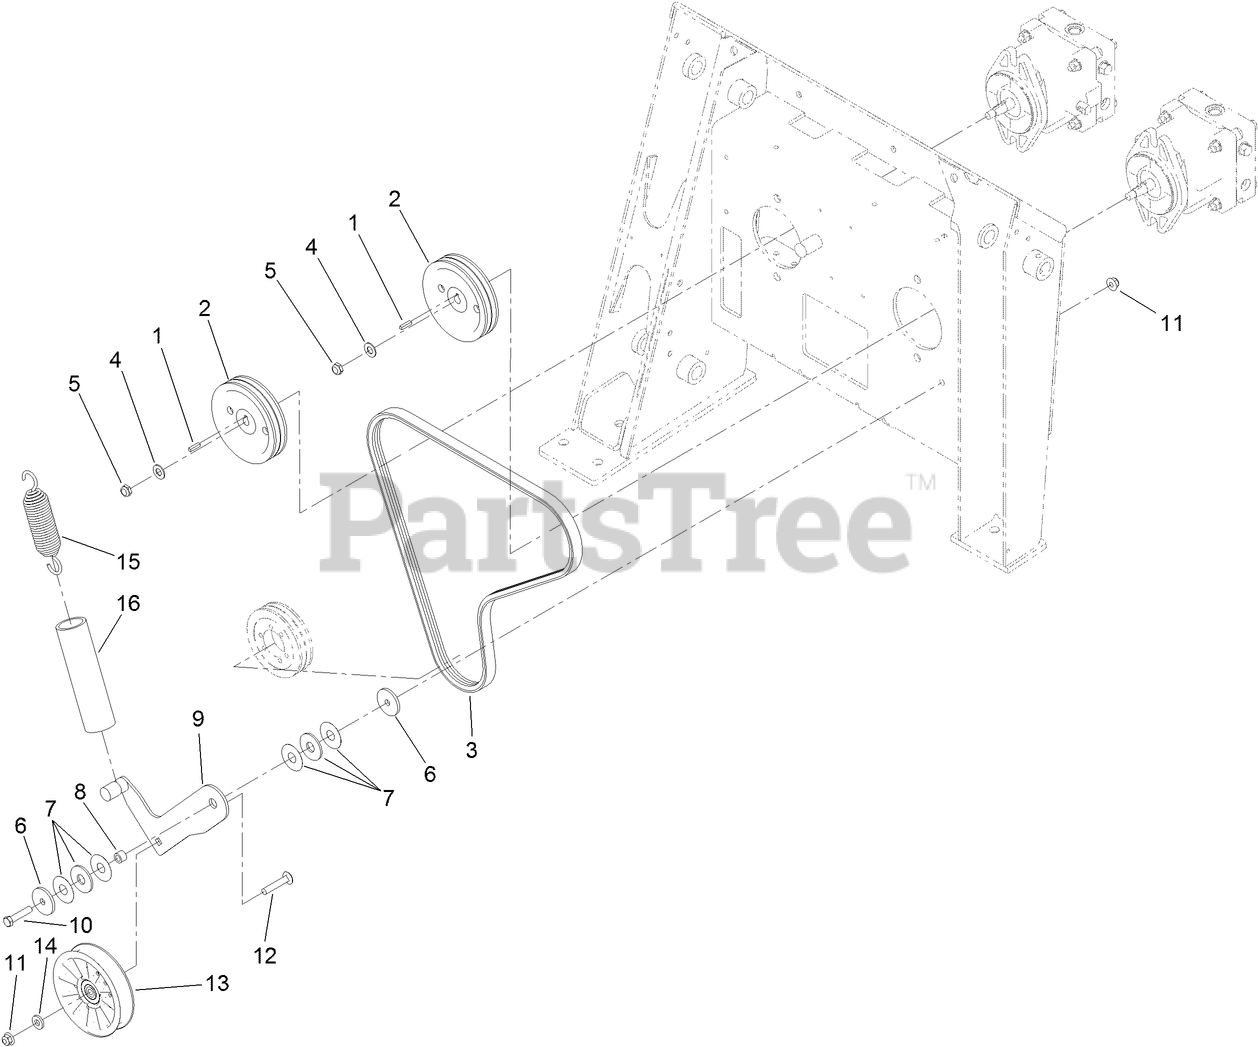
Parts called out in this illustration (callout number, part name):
2	PULLEY-3V
3	V-BELT
4	WASHER-FLAT
5	NUT-LOCK, NI
6	WASHER-PLAIN
7	WASHER-FRICTION, COMPOSITE
8	SPACER
9	ARM-IDLER
10	SCREW-HH
11	NUT-HF, NI
12	BOLT-CARRIAGE
13	PULLEY-IDLER
14	SPACER
15	SPRING-EXTENSION
16	RETAINER-SPRING
